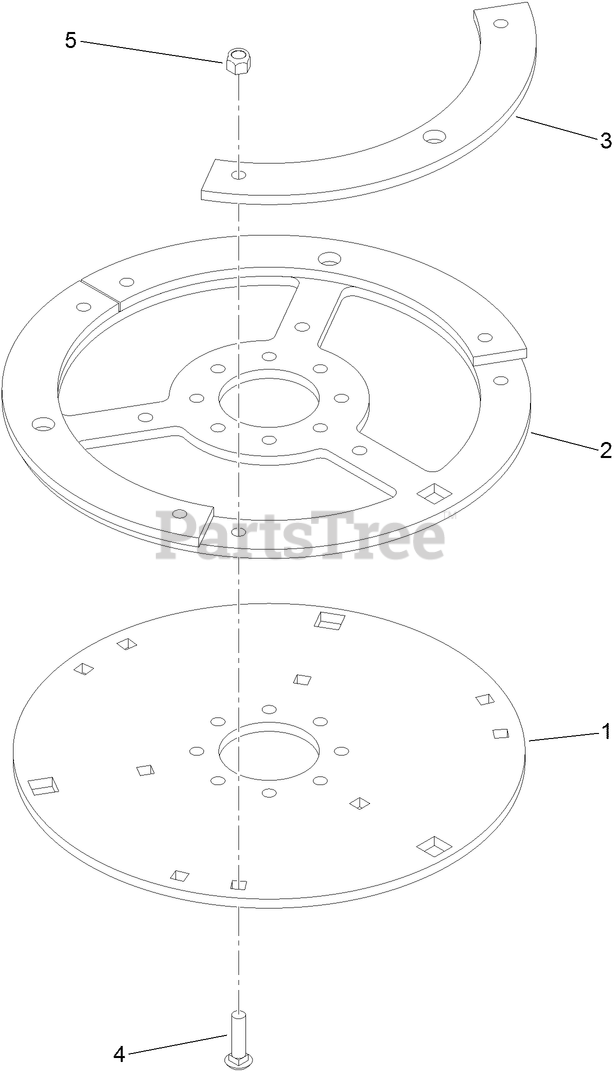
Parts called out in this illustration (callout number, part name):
1	PLATE-LOWER
2	PLATE-MIDDLE
3	PLATE-UPPER
4	BOLT,CARRIAGE,5/8-11X2-1/2 GR5 BLK ZN
5	NUT-LOCK, NI
